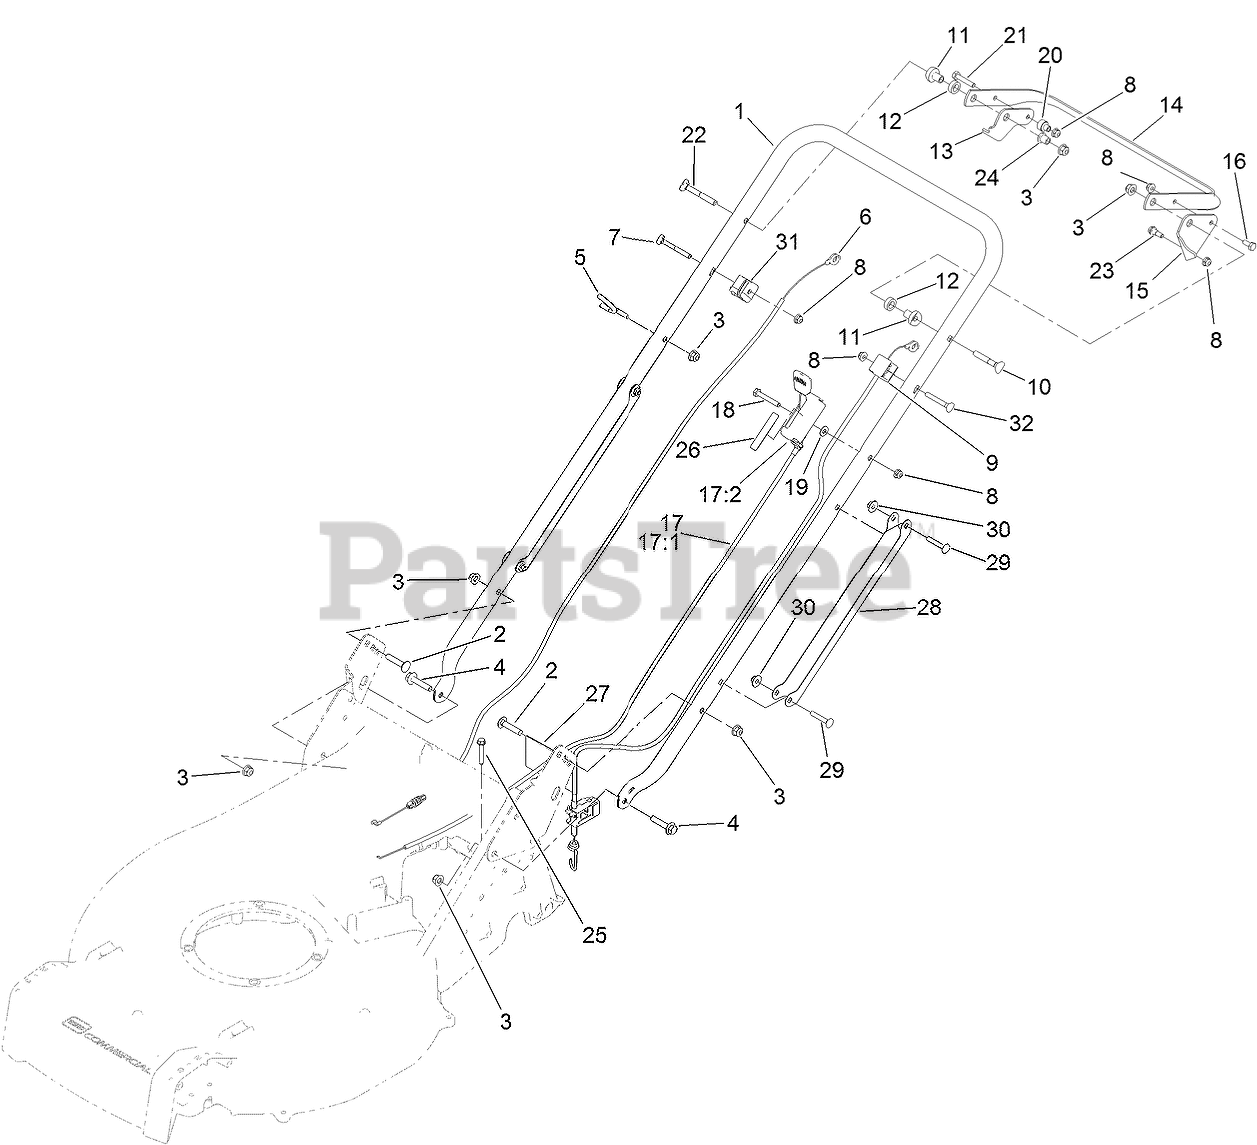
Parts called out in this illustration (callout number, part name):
2	BOLT-CARR
3	NUT-HF, NI
4	SCREW-HHF
5	GUIDE,ROPE
6	CABLE-BRAKE
7	SCREW-HANDLE
8	NUT-HF
9	CABLE-TRACTION
10	SCREW-HANDLE
11	SPACER-SUPPORT
12	SPACER-NYLON
13	LEVER-CONTROL, BRAKE
14	BAR-CONTROL, ZONE START
15	LEVER-CONTROL, TRACTION
16	SCREW-HH
17	CONTROL-THROTTLE/CHOKE
17:1	CABLE-THROTTLE
17:2	CONTROL-THROTTLE
18	SCREW-HH
19	WASHER-FLAT
20	SPACER-STEPPED
21	SCREW-HH
22	SCREW-HANDLE
23	BOLT-SHOULDER
24	SPACER
25	SCREW-HWH
26	DECAL-THROTTLE, CHOKE
28	GUARD-CABLE, HANDLE
29	SCREW-CARR
30	NUT-HF
31	ANCHOR-CABLE
32	SCREW
